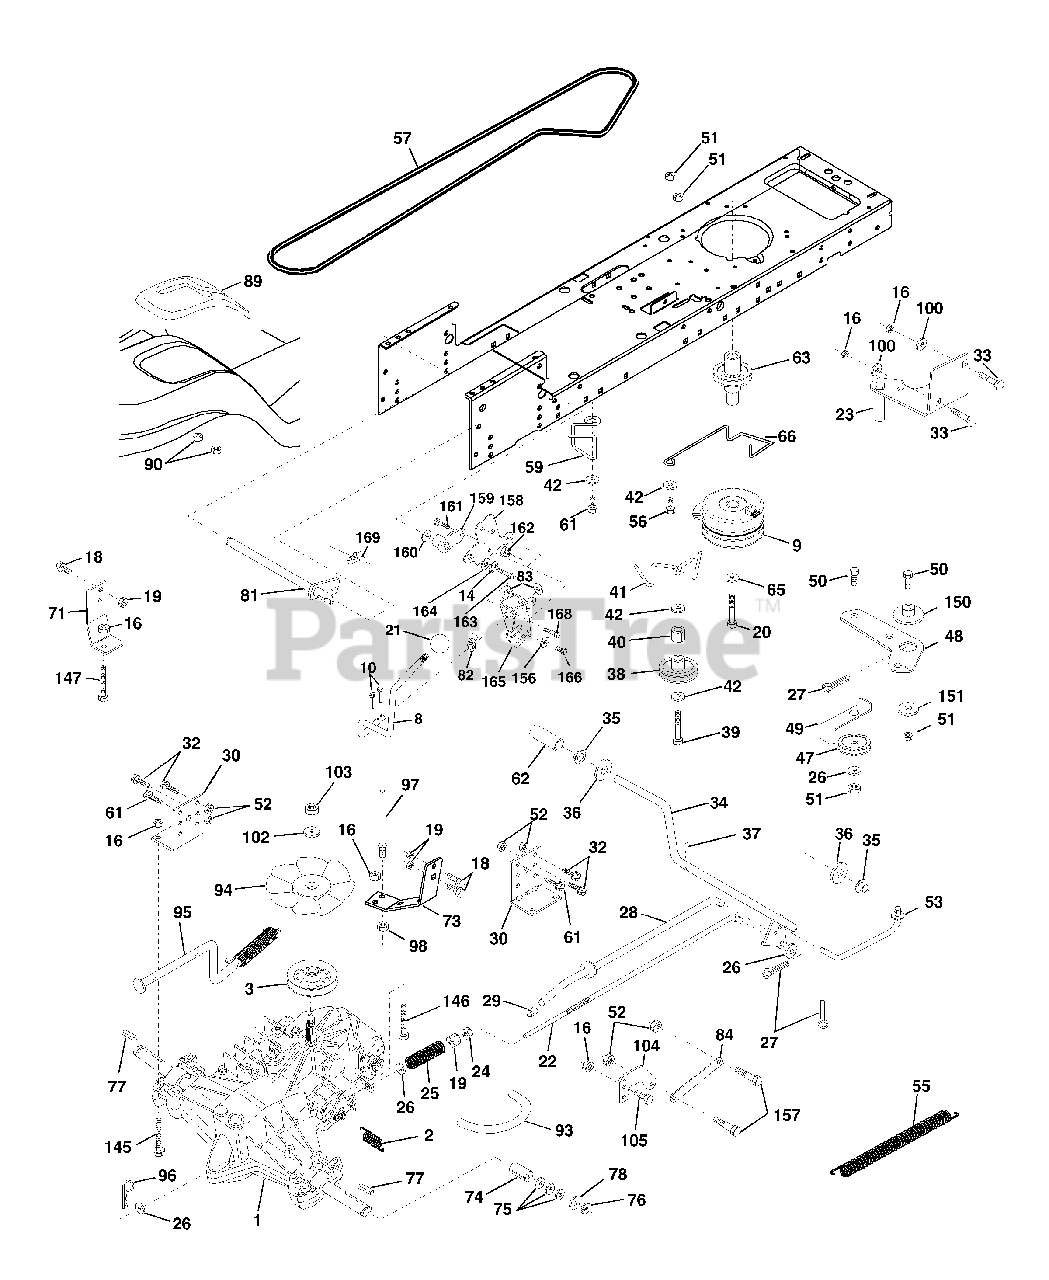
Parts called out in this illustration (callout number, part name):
2	Spring, Return, Brake
3	Pulley, Transaxle Hydro 750 LT
8	Rod Shift Fender Adjust LT
9	Clutch Electric
10	Pin Cotter 1/8 x 1 CAD
14	Washer Lock Hvy Helical
16	Nut Lock Hex W/Ins. 5/16-18 Unc P
18	Bolt Fin Hex 3/8-16 Unc x 1 Gr.5
19	Nut Lock Hex W/Ins 3/8-16 Unc
20	Bolt, Hex 7/16-20 x 4-1/4 Ga. 5
21	Knob Deluxe 1/2-13 UNC BLK/BLK
22	Rod, Brake Hydro
23	Bracket Asm Mtg CL
24	Nut Hex Jam 3/8-16 UNC
25	Spring, Brake Rod
26	Washer
27	Pin Cotter 1/8 x 3/4 CAD.
28	Rod, Parking Brake
29	Cap,Parking Brake
30	Bracket, Transaxle
32	Bolt Hex Hd 5/16-18 Unc x 3/4
33	Bolt Carriage 5/16-18 UNC x 3/4
34	Shaft, Foot Pedal
35	Bearing, Nylon
37	Pin, Roll
38	Pulley, Idler, Flat
40	Spacer Split
41	Keeper, Belt Idler
42	Washer 13/32 x 13/16 x 12 Ga
47	Pulley, Idler, V-Groove Plastic
48	Bellcrank Clutch Grnd Drv Stl
49	Retainer, Belt Style Spring
50	Bolt
52	Nut Crown Lock 5/16-18
53	Link, Clutch
55	Spring, Return, Clutch
56	Bolt, Fin Hex 3/8-16 UNC x 1 1/4
57	V-Belt, Ground Drive
59	Keeper, Center Span
61	Screw Thdrol. 3/8-16 x 3/4 Ty. TT
62	Cover, Pedal Premium
63	Pulley, Engine
65	Washer Lock Hvy HLCL Spr 7/16
66	Keeper Belt Engine
71	Strap Torque Lh Hydro 18/20" T
73	Strap Torque Rh Hydro 0650
74	Spacer, Split
75	Washer 25/32 x 1-1/4 x 16 Ga.
77	Key, Square
78	Washer 25/32 x 1-5/8 x 16 Ga
81	Shaft Asm Cross Tapered
83	Washer 17/32 x 3/4 x 16 Ga.
84	Link Transaxle
89	Console, Hydro
90	Nut Self-Thd Wsh-Hd 1/4 Zinc
93	Line Fuel Hydro 4"
94	Fan, Hydro 7"
95	Control Asm. Bypass Hydro
96	Retainer Spring 1" Zinc/Cad
97	Keeper Belt Rh Hydro 0750.18/20"
98	Nut Keps Hex 3/8-16 Unc
100	Washer 11/32 x 3/4 x 16 Ga.
102	Washer Belleville .501D x 1.50D
103	Nut Hex Jam Toplock 1/4-20 Unf
104	Arm, Control Hydro
105	Screw Cap Hex 5/16 x 18 x 1
106	Bolt Fin Hex 5/16-18 Unc x 1-1/4
144	Washer 11/32 x 5/8 x 16 Ga.
145	Bolt Hex 5/16-18 Gr. 5
146	Bolt Hex Flghd 5/16-18 x 2-1/4
147	Bolt Hex Flghd 5/16-18 x 1-1/2
150	Bushing Bellcrank Grd Drive
151	Washer 13/32 x 2 x 10 Ga.
156	Washer Srrted 5/16 ID X 1 X .125
157	Bolt Shoulder 5/16-18 Unc - 2A
158	Bracket Shift Mount
159	Hub Tapered Flange Shift LT
160	Washer 29/32 x 1-1/4 x 16 Ga.
161	Bolt Rdhd Sqnk 1/4-20 x 3/4 Gr. 5
162	Nut Crownlock 1/4-20 Unc
163	Bolt Hex Fin 1/4-20 Unc x 1 Gr. 5
164	Washer 5/8 x .281 x 10 Ga.
165	Bracket Pivot Lever
166	Screw 5/16-18 x 5/8
168	Bolt Shoulder 5/16-18 x .561
169	Plate Fastening LT
